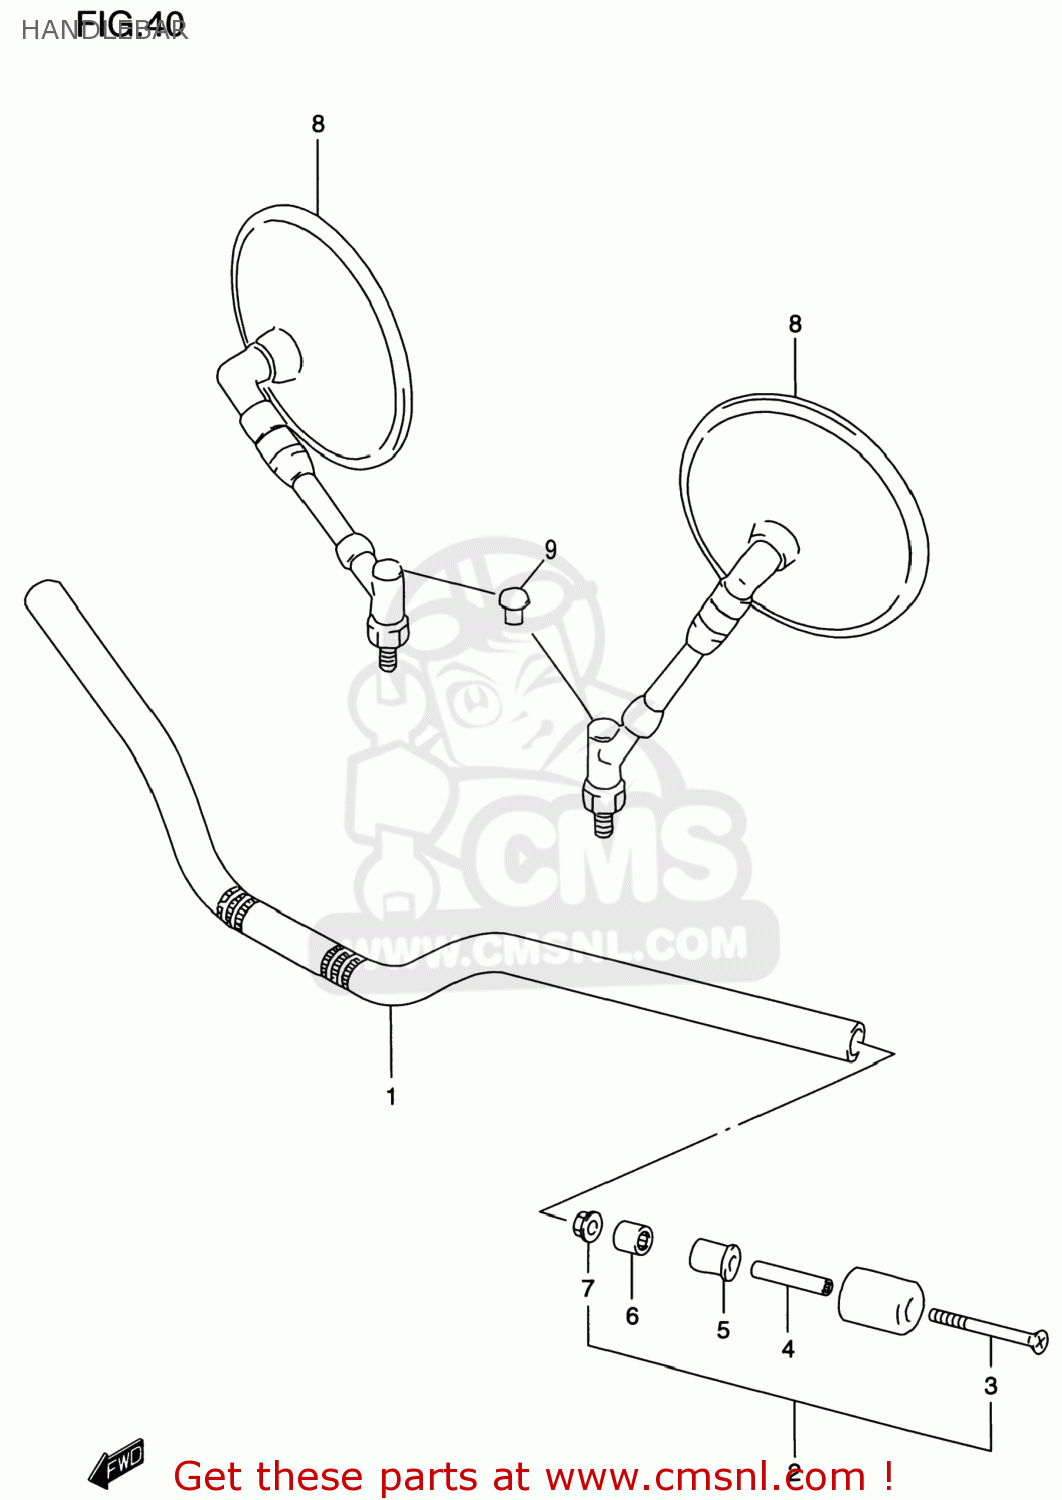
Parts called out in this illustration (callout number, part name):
1	HANDLEBAR
2	BALANCER SET,HANDLEBAR
3	SCREW(6X125)
4	SPACER,EXPANDER
5	EXPANDER,HANDLE BALANCER OUT
6	EXPANDER,HANDLE
7	NUT
8	MIRROR ASSEMBLY,REAR VIEW
9	CAP
